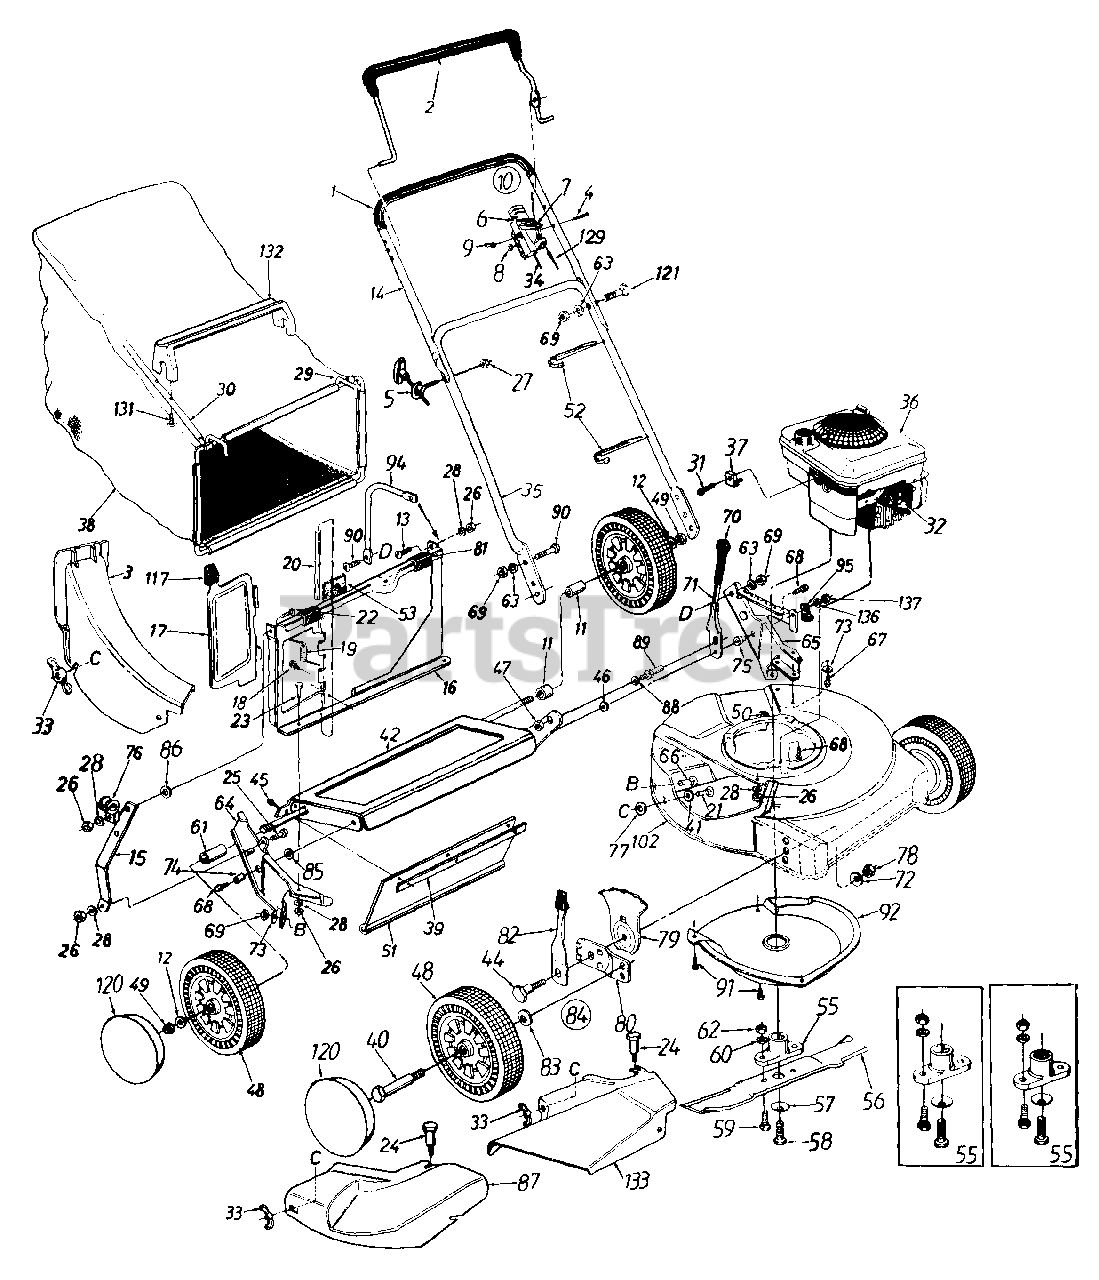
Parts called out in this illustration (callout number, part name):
1	Grip
2	Control Handle Ass'y. - L.H.
3	Top Discharge Chute Ass'y.
4	Oval C-Sunk Scr.
5	Rope Guide Bolt
6	Throttle Body
7	Throttle Lever
8	Spr. Wash. .66" I.D.
9	Hex L-Nut 1/4-20 Thd.
10	Throttle Box Comp.
11	Spacer .526" I.D. x .690" O.D. x .640" Lg.
12	Fl. Wash. .385" I.D. x .87" O.D.
13	Truss Mach. Scr. 1/4-20 x .62"
14	Upper Handle
19	Torsion Spring
20	Pivot Pin
21	Carriage Bolt 1/4-20 x .62"
22	Truss Mach. Scr. 1/4-20 x .75"
23	Hex Bolt 1/4-20 x .50" Lg.
24	Shoulder Bolt .312" Dia. x .18" Lg. Special
25	Hex Bolt 1/4-20 x .62" Lg.
26	Hex Nut 1/4-20 Thd.
27	Hex L-Nut 1/4-20 Thd.
28	L-Wash. 1/4" I.D.
30	Upper Bag Support
31	Hex Self-Tap Scr. #10-32 x .62"
32	Spark Plug Insulator
33	Wing Nut w/Washer
34	Throttle Control Wire 61"
35	Lower Handle
37	Cable Clamp
38	21" Top Discharge Grass Bag
39	Retaining Strip
40	Shld. Bolt .498" Dia. x 1.45"
41	Fl-Wash. .344" I.D. x .62"
45	Hex AB-Tap Scr. 1/4 x .62"
46	Fl-Wash. .38" I.D. x 1.0"
47	Hex Jam Nut 3/8-24 Thd.
48	Wheel Ass'y. Comp.
49	Hex Ins. Top L-Nut 3/8-16 Thd.
51	Rear Flap 3.75" x 17.30" Lg.
52	Cable Tie
53	Foam Strip 1" Lg.
55	Blade Adapter Kit
56	21" Blade
57	Bell-Wash. .39" I.D.
58	Hex Bolt 3/8-24 x 1 5" Lg.
59	Hex Bolt 3/8-24 x 1" Lg.
60	L-Wash. 3/8" I.D.
61	Sleeve .526" I.D. x .69"
62	Hex Nut 3/8-24 Thd.
63	L-Wash. 5/16" I.D.
64	R.H. Handle Wheel Brkt. Ass'y.
65	L.H. Handle Wheel Brkt. Ass'y.
66	Carriage Bolt 5/16-18 x .62"
67	Hex Wash. Hd. B-Tap Scr. 5/16-18
68	Hex Wash. Hd. TT-Tap Scr. 3/8-16
69	Hex Nut 5/16-18 Thd.
71	Height Adj. Lever
72	Bell-Wash. .39" I.D. x 1.38" O.D.
73	Bell-Wash. 5/16" I.D.
74	Spacer .383" I.D. x 503" O.D.
75	Shld. Spacer .500" Dia.
76	Rope Guide
77	Bolt Retainer 1/4 x .50" O.D.
78	Hex Nut 3/8-16 Thd.
79	Height Adj. Plate
81	Panel Clip
82	Spring Lever Ass'y. w/Knob
83	Bell-Wash. .38" I.D. x .88" O.D.
84	Height Adj. Ass'y. Comp. - R.H.
85	Fl-Wash. 3/8" I.D. x 1" O.D.
86	Fl-Wash. .285" I.D. x 1.25" O.D.
87	Mulching Plug
88	L-Wash. 3/8" I.D.
89	Shld. Pin 3/8-24 x 1.43" Lg.
90	Truss Mach. Scr. 5/16-18 x .75"
91	Hex Wash. Hd. Tap Scr. 1/4 x .5" Lg.
92	Mulching Baffle
94	Catcher Panel Support Arm
95	Clamp
120	Hub Cap
121	Curved Carr. Bolt 5/16-18 x 1.38" Lg.
129	Control Cable - 47" Lg.
131	Hex AB-Tap Scr. #12 x 1.0"
132	Bag Handle
133	Side Chute Deflector Ass'y.
136	Fl-Wash. .385" I.D. x .87" O.D.
137	Hex Patch L-Nut 3/8-24 Thd.
